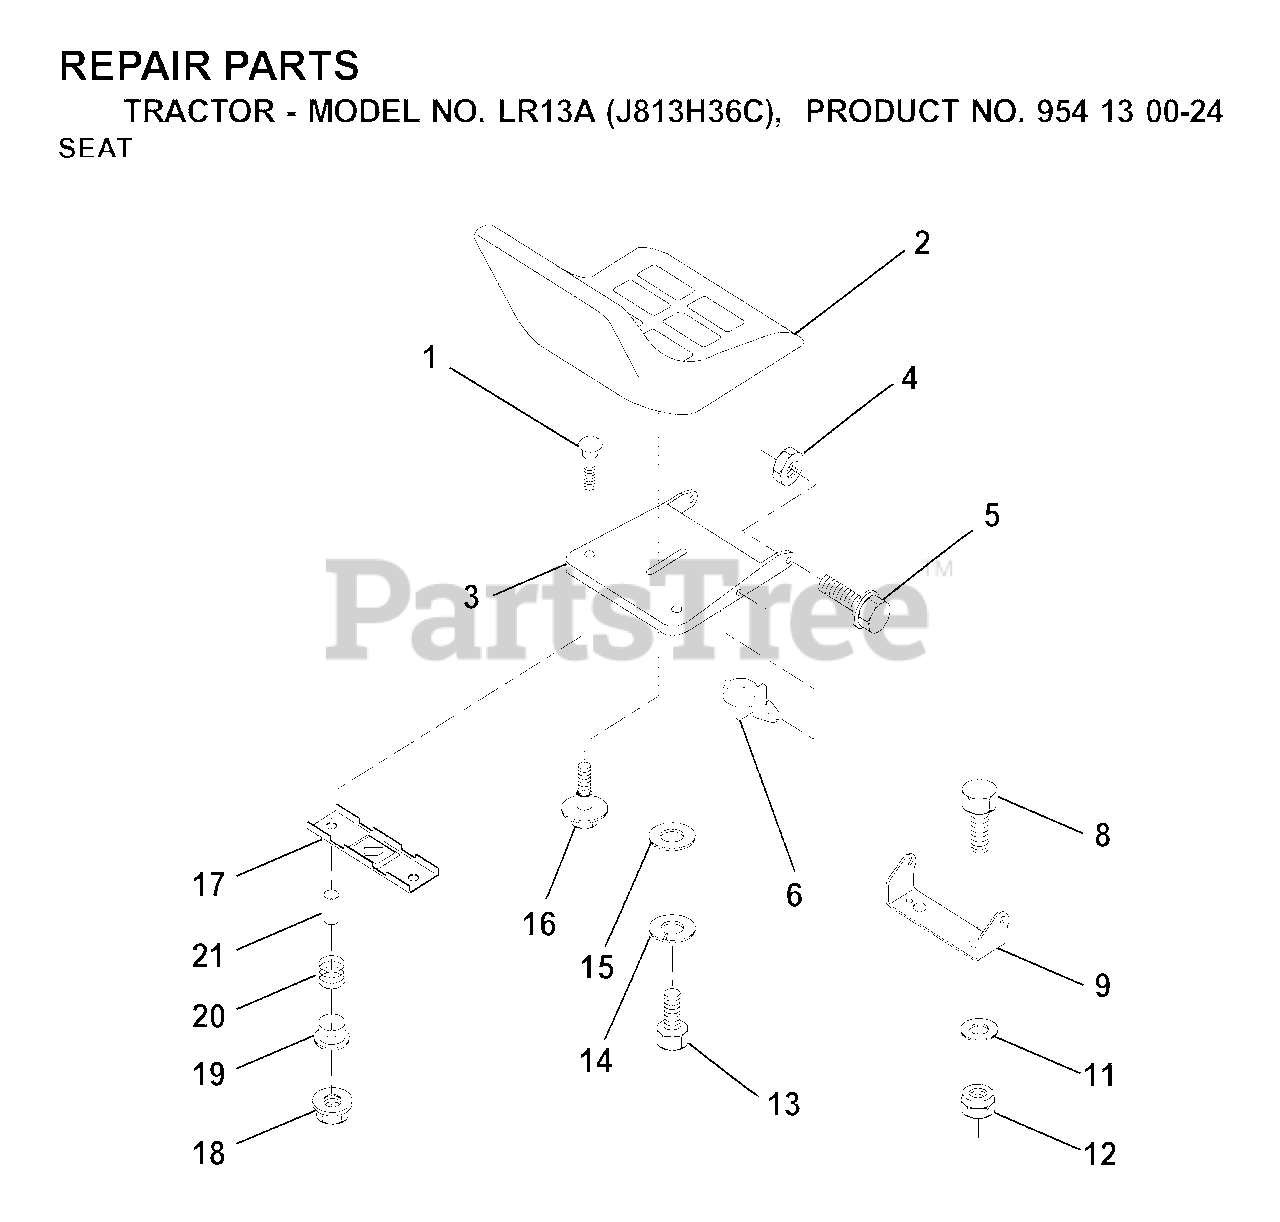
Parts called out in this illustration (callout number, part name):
1	BOLT.ROUND.HEAD.SQUARE.NECK
3	PAN, SEAT
4	NUT.71038.31-18.HEX.NYLOCK
5	BOLT SHOULDER 5/16-18
6	PUSH CLIP
8	BOLT
9	SEAT PIVOT BRKT
10	CLIP,INSULATOR
11	WASHER 12/32X2X10GA
12	NUT
13	BOLT
14	LOCKWASHER
16	BOLT,SHOULD
17	BRKT SWITCH
18	NUT T
21	SPACER SPLIT 28X.96
